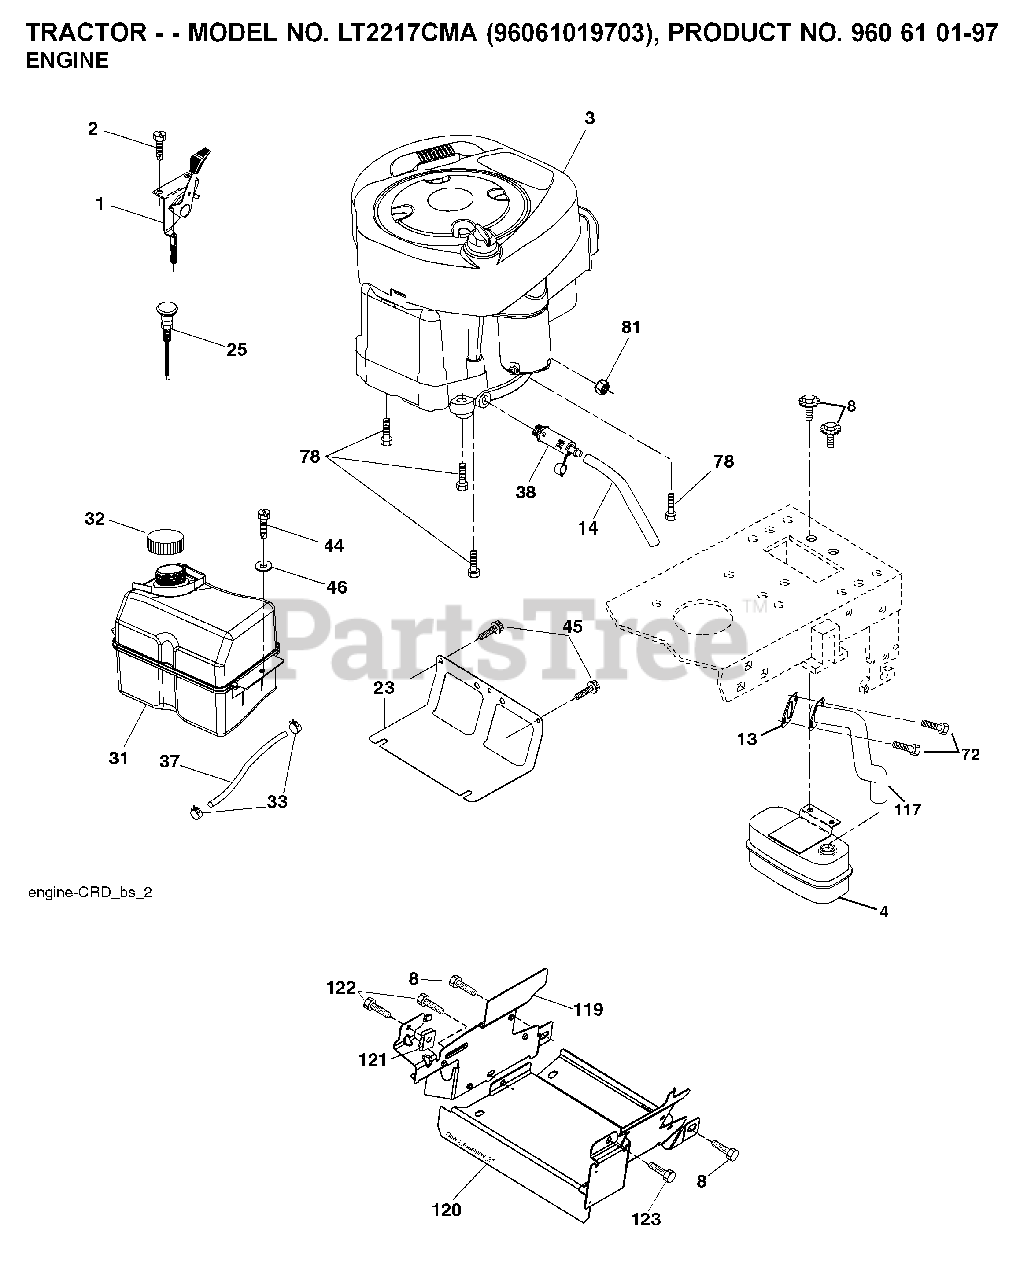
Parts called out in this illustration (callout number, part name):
1	CONTROL TH/CH FLAG
2	SCREW
4	MUFFLER.SINGLE.CYL.KOHL/B&S
8	BOLT, 5/16-18 X 1 3/4
13	REPL BY 532 27 22-93
14	TUBE, DRAIN OIL ASM.
23	SHEILD.BROWNING.DBR.GUARD
29	ARRESTER SPARK (OPTIONAL)
32	FUEL CAP
33	HOSE CLAMP
37	LINE.FUEL.20
38	PLUG DRAIN OIL EASY
44	SCREW HEXWSHR 1/4-20X3/4
45	SCREW, 3/8-16X3/4
72	SCREW.SOCKET HD.5/16-1
78	SCREW.3/8-16
81	NUT
117	EXHAUST.TUBE.B&S.
122	SCREW.1/4-20X5/8
123	SCREW, 5/16-18 X 1/2
